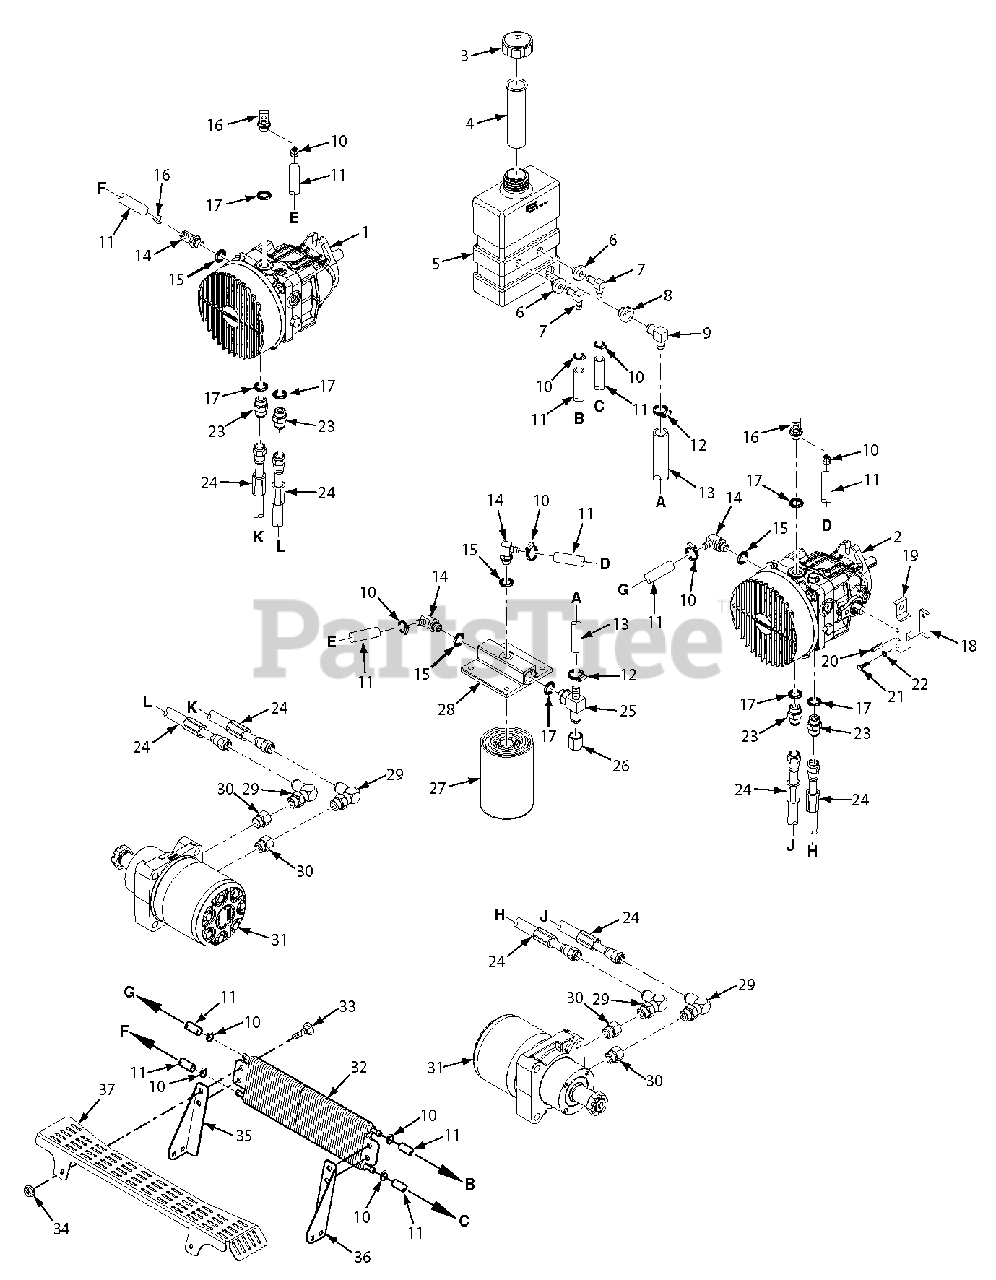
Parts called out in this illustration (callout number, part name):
1	Pump, RH w/Fan
1	Pump, RH w/Fan (26EFI Only)
2	Pump, LH, w/Fan
3	Cap, Hydraulic Tank
4	Insert, Filler Neck
5	Hydraulic Tank Assy., STTII
6	Bushing, .56 Dia. Viton
7	Fitting, 90 Degree - .38 Hose
8	Bushing, .78 Dia Viton
9	Fitting, 90 Degree - .50 Hose
10	Clamp, Hose
11	Hose, 3/8 Pushlock (order by inch)
12	Clamp, Hose
13	Hose, 1/2 Pushlock (order by inch)
14	Elbow, 90 Degree - 9/16 O-Ring
15	O-Ring, 9/16-18 Thread
16	Elbow, 90 Degree - 3/4 O-Ring
17	O-Ring, 3/4-16 Thread
18	Plate, Pump Control Clamp
19	Block, RH Pump Control
19	Block, LH Pump Control
20	Pin, 7/32 x 1"
21	Bolt, Hex Head 1/4-20 x 1-1/2"
22	Lockwasher, 1/4
23	Fitting, Union 3/4-16 JIC X O-Ring
24	Hose Assembly
25	Tee Fitting, 3/4 - O-Ring
26	Cap, JIC
27	Filter, Spin-On
28	Filter Head Assembly
29	Elbow, 90 Degree - 5/8 Tube
30	O-Ring Bushing, 5/8 Tube
31	Wheel Motor, Parker TG - 18ci.
32	Cooler, Transmission
33	Bolt, Carriage 1/4-20 x 3/4
34	Nut, Serrated Flange 1/4-20
35	Mounting Bracket, Cooler - RH
36	Mounting Bracket, Cooler - LH
37	Screen Guard, Kohler EFI
37	Screen Guard, Briggs & Stratton 35BV
37	Screen Guard, Briggs & Stratton 37BV-EFI
